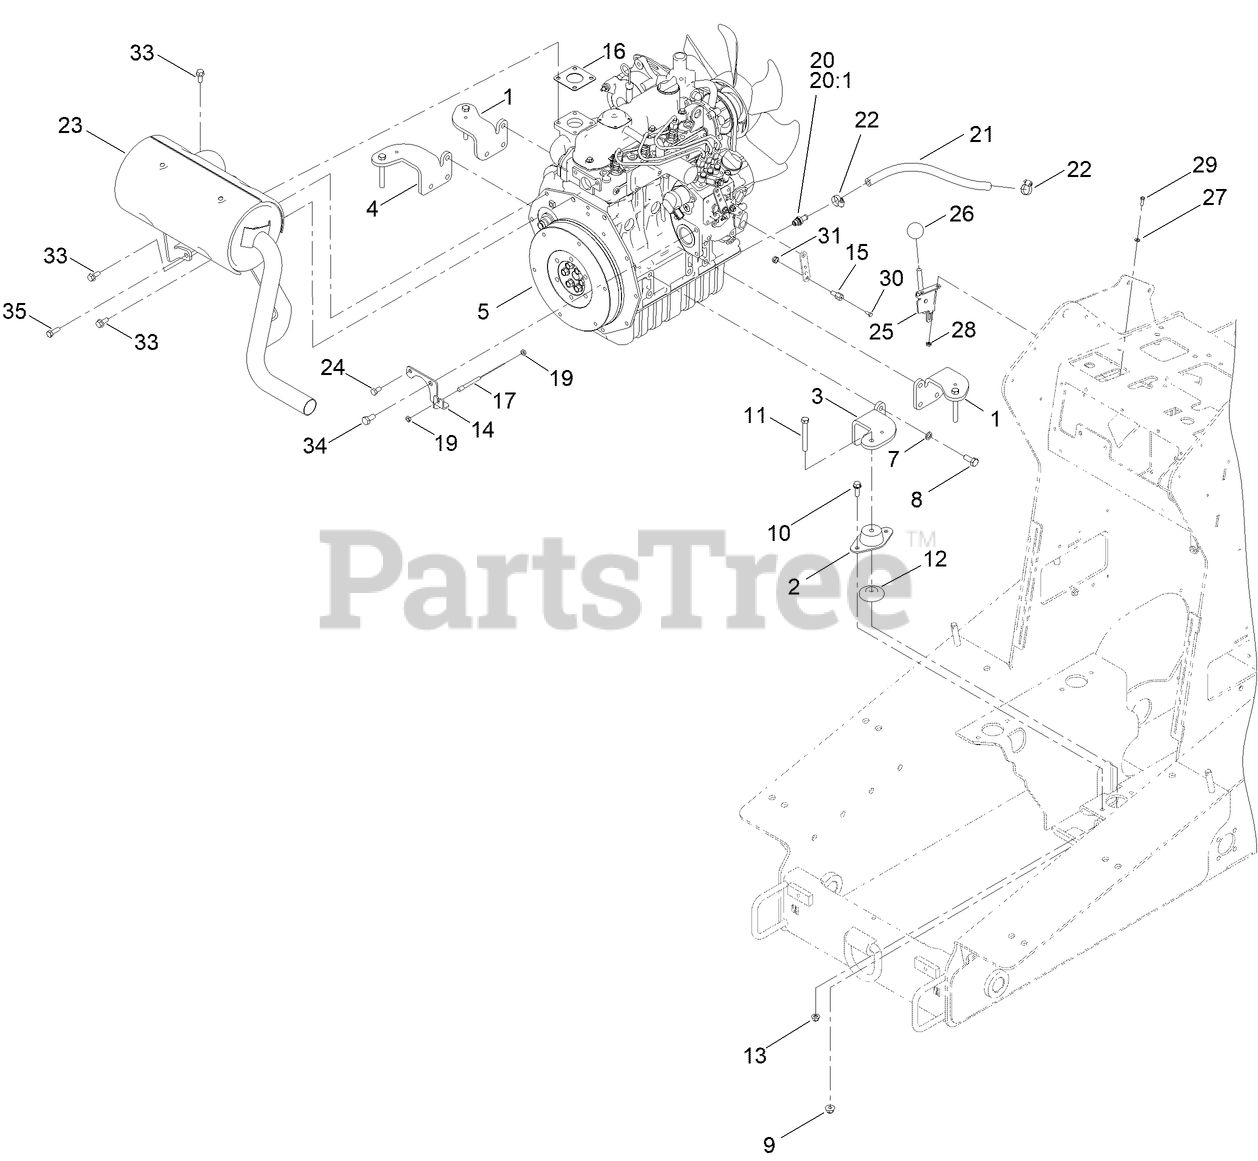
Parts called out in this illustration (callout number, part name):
1	MOUNT-ENGINE
2	MOUNT-ENGINE
3	MOUNT-ENGINE LH
4	MOUNT-ENGINE, RH
5	ENGINE-KUBOTA, D1305
7	WASHER-LOCK
8	SCREW-HH
9	NUT-HF, NI
10	SCREW-HHF
11	SCREW-HH
12	SUPPORT-ISOLATOR
13	NUT-HF, NI
14	BRACKET-THROTTLE
15	SWIVEL-THROTTLE
16	GASKET-MUFFLER
17	CABLE-THROTTLE
19	NUT-JAM
20	FITTING-BARB
20:1	SEAL-ORING
21	HOSE-OIL DRAIN
22	CLAMP-HOSE
23	MUFFLER-DIESEL
24	SCREW-HH
25	LEVER-CONTROL
27	WASHER-FLAT
28	NUT-KEPS
30	SCREW-HH
31	NUT-LOCK, NI
33	SCREW-HHF
34	SCREW-CAP
